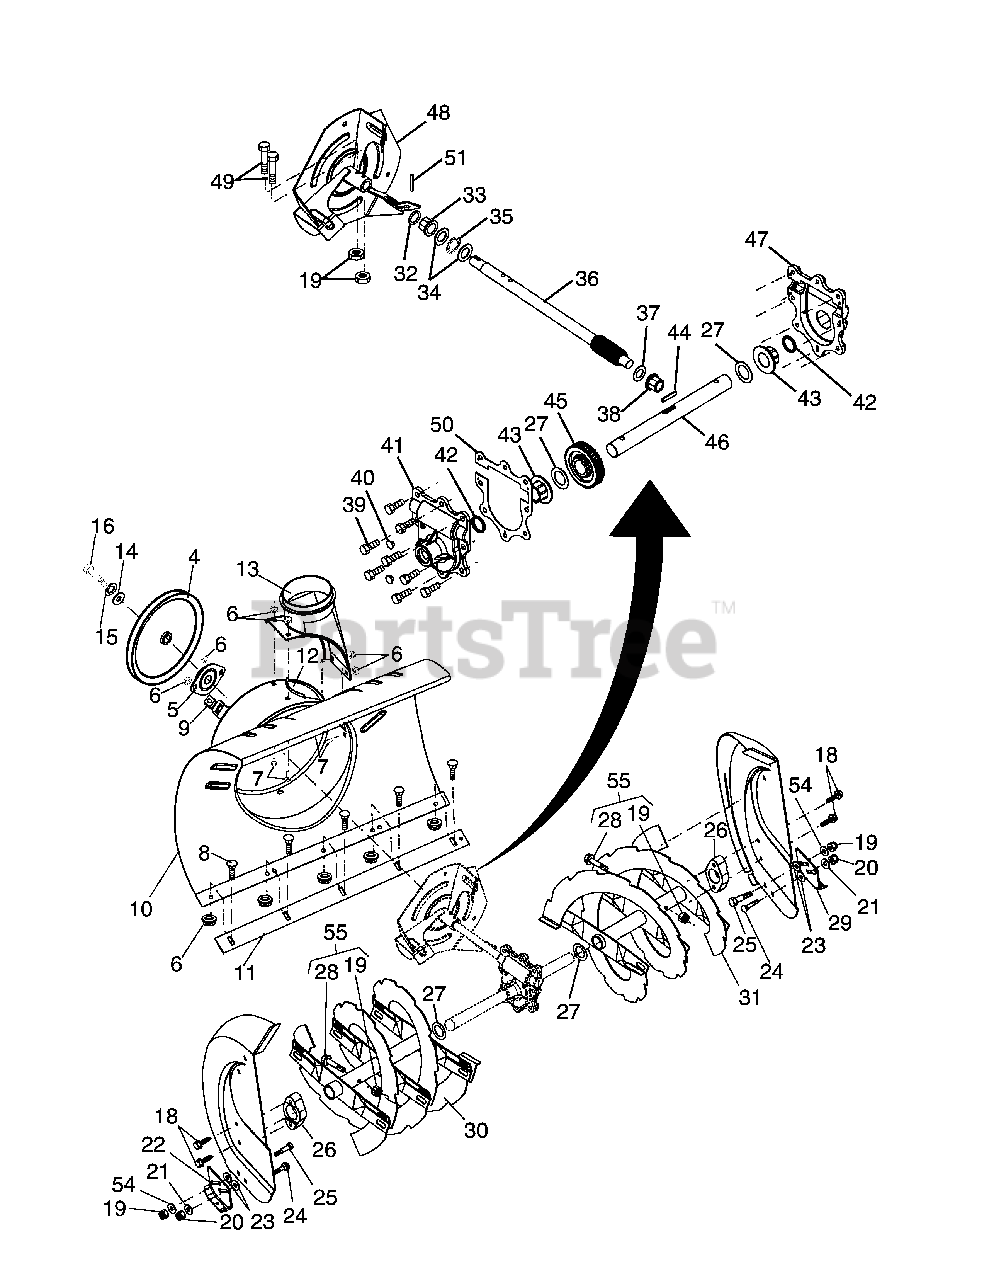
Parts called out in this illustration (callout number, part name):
4	Pulley, Impeller
5	Bearing Assembly, Flange
6	Nut, Hex Flange 5/16-18
7	Bolt, Flat Head, Carriage 5/16-18 x 5/8
8	Bolt, Carriage 5/16-18 x 5/8
9	Nut, Cage 3/8-16
10	Housing, Auger
12	Bracket, Corner Discharge
13	Base, Discharge Chute
14	Washer, Flat
15	Washer, Lock 5/16
16	Screw, Hex Head 5/16-18 x 3/4
18	Screw, Hex Head 5/16 x 1
19	Nut, Hex Lock 1/4-20
20	Nut, Hex Lock 5/16-18
21	Washer, Flat 5/16
22	Skid Plate, RH
23	Washer, Nylon, Friction
24	Bolt, Carriage 5/16-18 x 3/4
25	Bolt, Shoulder 1/4-20
26	Bearing, Auger
27	Washer, Thrust, 1"
28	Bolt, Shear
29	Skid Plate, LH
30	Auger Assembly, RH
31	Auger Assembly, LH
32	O-Ring
33	Bushing, Flange 3/4
34	Washer, Thrust 3/4
35	Bearing, Thrust 3/4
36	Shaft, Impeller
37	Washer, Thrust 5/8
38	Bushing, Flange 5/8
39	Screw, Hex Head 5/16-18 x 3/4
40	Plug, Case
41	Housing, Gearbox, RH
43	Bushing, Flange, 1"
44	Key, Square 1/4 x 1/4 x 7/8
45	Gear, Worm
46	Shaft, Auger
47	Housing, Gearbox, LH
48	Impeller Assembly
49	Screw, Hex Head 1/4-20 x 1-5/8
50	Gasket, Gearbox
51	Pin, Roll 3/16 x 1-1/8
54	Washer, Flat 1/4
55	Kit, Shear
